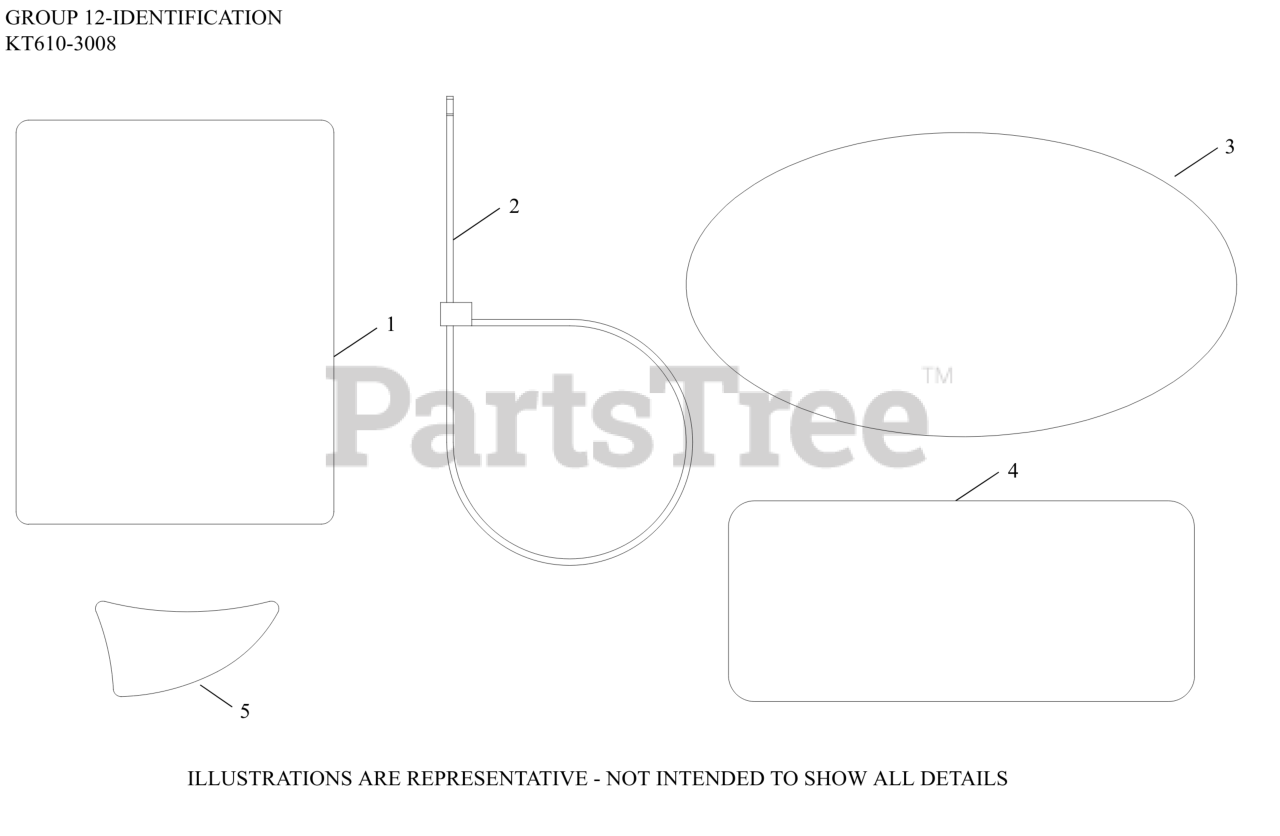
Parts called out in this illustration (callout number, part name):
1	LABEL, CLEAR LAMINATION
3	LABEL, 6600 SERIES (19HP)
4	LABEL, CANADIAN COMPLIANCE
5	LABEL, SMART CHOKE
